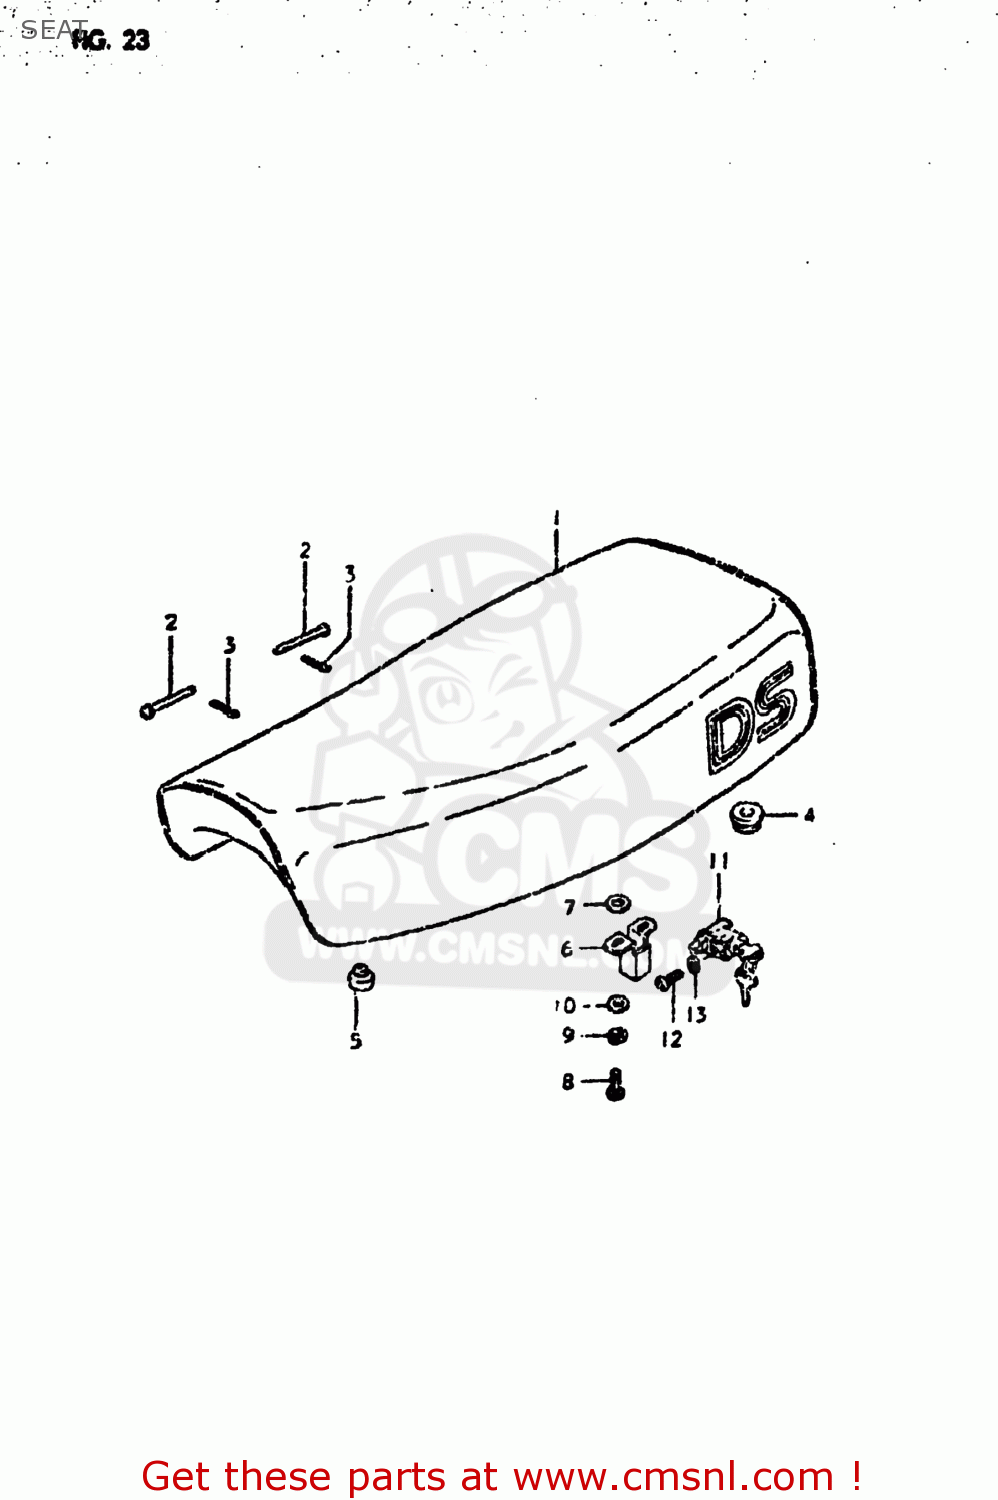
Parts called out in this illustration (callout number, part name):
1	SEAT ASSEMBLY
2	PIN
3	PIN
4	CUSHION
5	CUSHION(11.5X22X20)
6	PLATE,CLAMP GUIDE
7	WASHER(8.5X18X1)
8	SCREW
9	LOCK WASHER
10	WASHER
11	LOCK ASSEMBLY,SEAT
12	SCREW
13	LOCK WASHER
